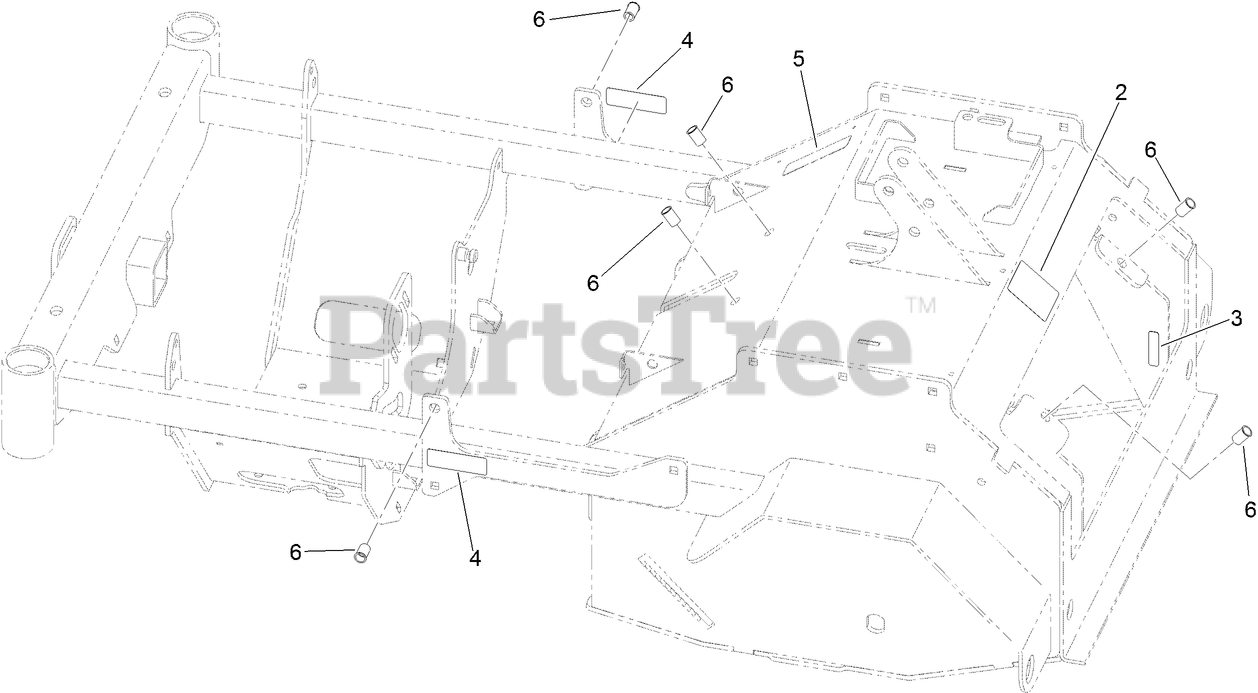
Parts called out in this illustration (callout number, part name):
2	DECAL-WARNING
3	DECAL-WARNING
4	DECAL-DANGER
5	DECAL-ARRESTER, SPARK
6	NUT-CLINCH
